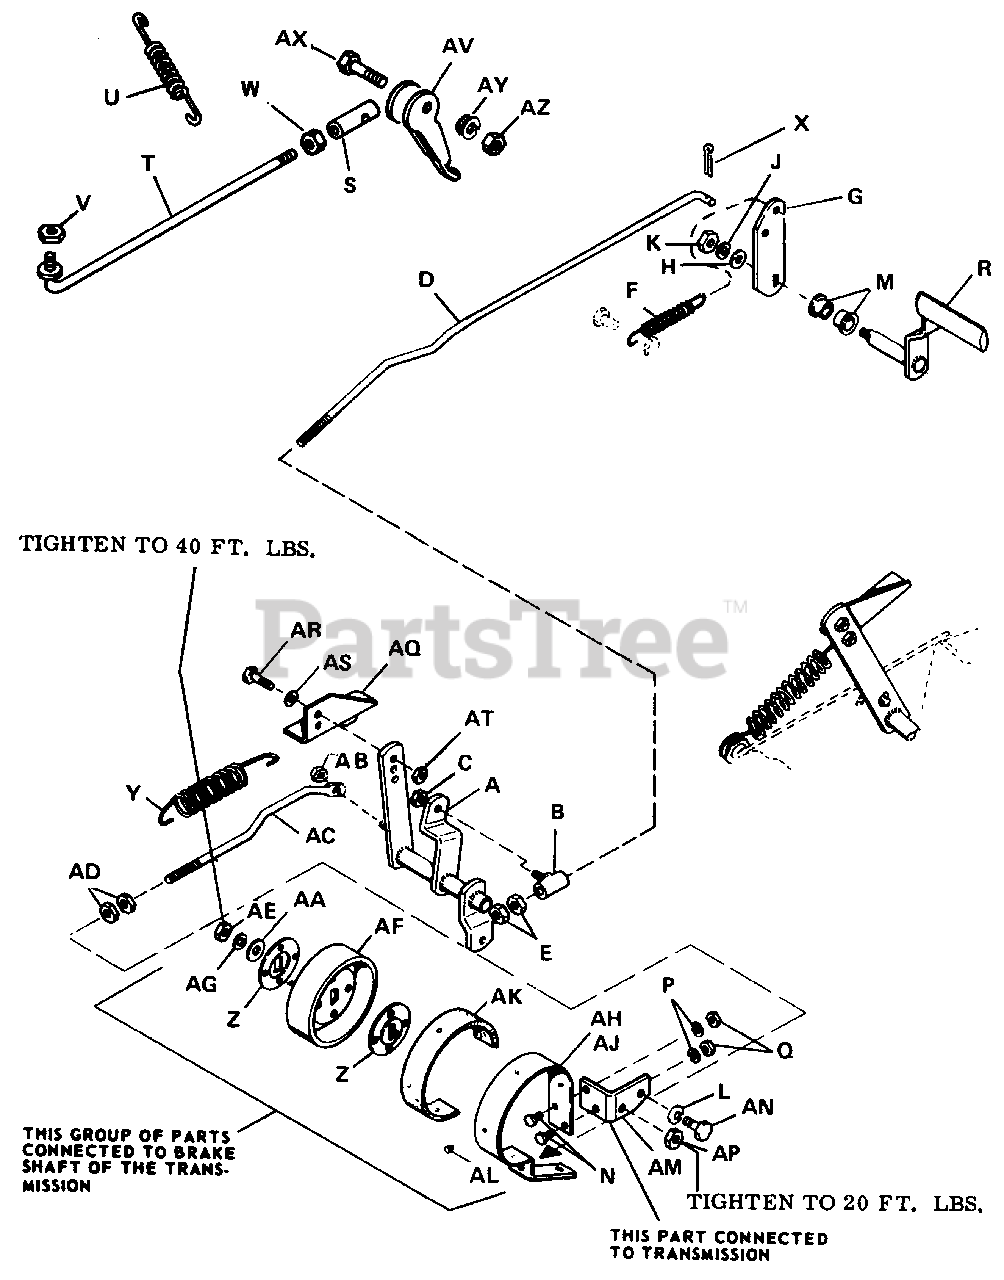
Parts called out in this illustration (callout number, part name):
A	Pivot Lever Assy.
B	Rod Guide Assy.
C	Hex Lock Nut, 5/16"-18
D	Brake and Clutch Rod
E	Hex Nut, 5/16"-18
F	Tension Spring
G	Foot Pedal Arm
H	Washer, Plain, 3/8"
J	Lock Washer, 3/8"
K	Hex Nut, 3/8"-16
L	Lock Washer, 3/8"
N	Hex Capscrew, 1/4"-20 x 3/4"
P	Lock Washer, 1/4"
Q	Hex Nut, 1/4"-20
R	Foot Pedal Assy.
T	Parking Brake Rod
V	Full Hex Nut, Lock, 5/16"-18 N.C.
W	Full Hex Nut, 5/16"-18 N.C.
X	Cotter Pin, 3/32" x 3/4"
Y	Tension Spring
Z	Special Washer
AA	Plain Washer, 3/8"
AB	Full Centerlock Nut, 5/16"-18
AC	Brake Rod
AD	Hex Nut, 3/8"-16
AE	Hex Nut, 7/16"-14
AF	Brake Drum
AG	Lock Washer, 7/16"
AH	Brake Band Assy.
AK	Brake Lining
AM	Brake Band Bracket
AN	Hex Capscrew, 3/8"-16 x 1"
AP	Hex Nut, 3/8"-16
AQ	Spring Bracket
AR	Hex Capscrew, 5/16"-18 x 3/4"
AS	Lock Washer, 5/16"
AT	Hex Nut, 5/16"-18
AU	Plain Washer, 7/16"
AV	Parking Brake
AW	Full Hex Lock Nut, 5/16"-18
AX	Hex Capscrew, 1/4"-20 N.C. x 1-1/4" SAE Grade 8
AY	Double Lock Washer, 1/4"
AZ	Nut, Hex Lock Full, 1/4"-20 N.C.
